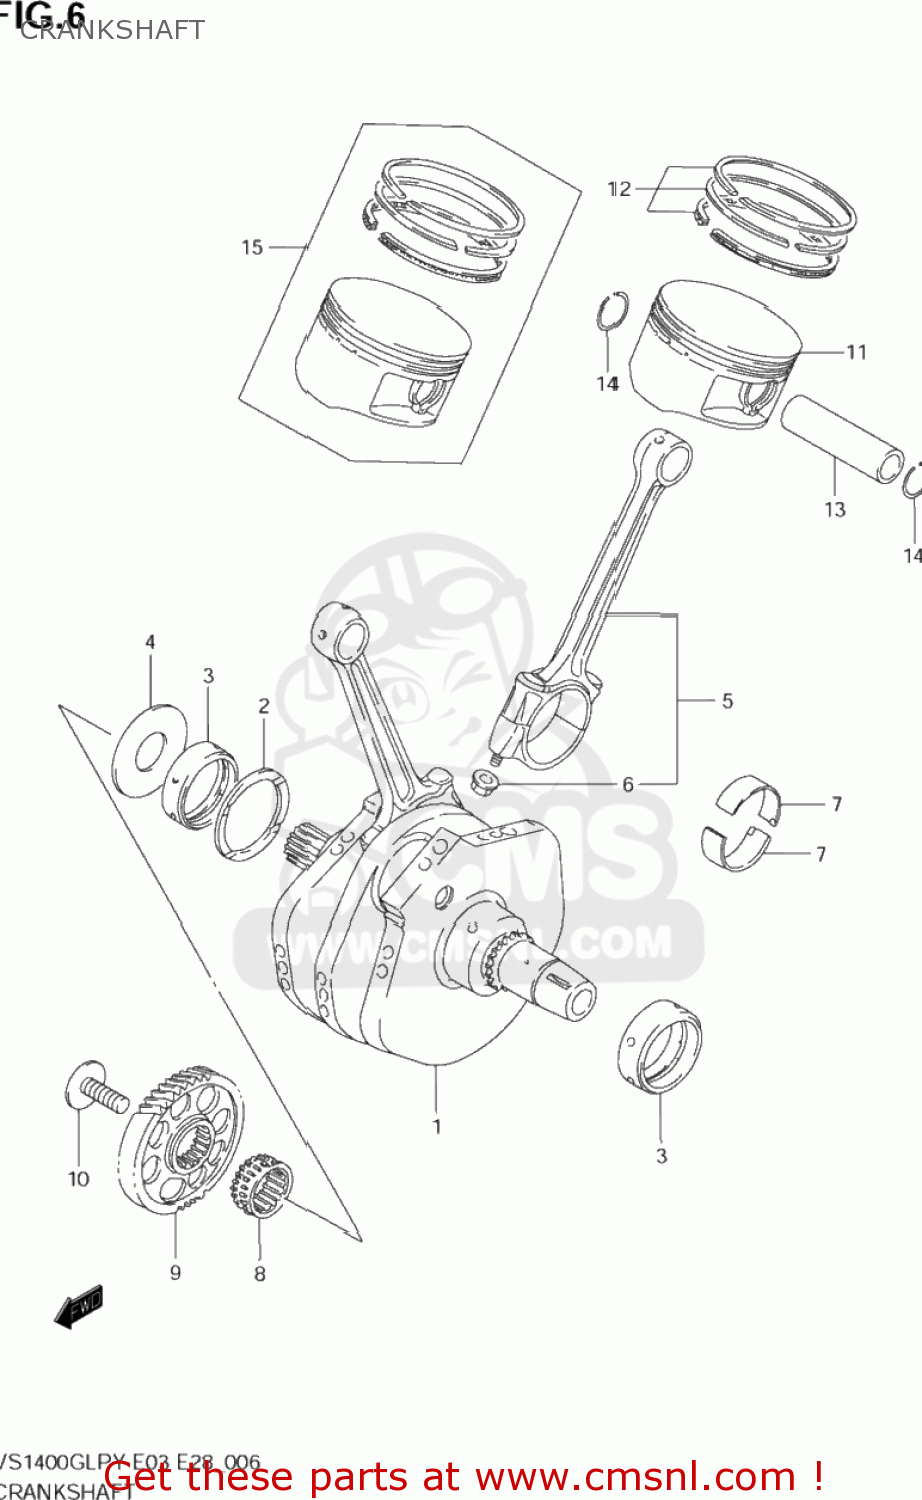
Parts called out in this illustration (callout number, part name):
1	CRANKSHAFT SET
2	PLATE,CRANK THRUST
3	METAL,CRANKSHAFT
4	WASHER,CRANK THRUST
5	CONNECTING ROD ASSY
6	NUT
7	METAL,CRANK PIN
8	SPROCKET,CAM CHAIN DRIVE,R
9	GEAR,PRIMARY DRIVE
10	BOLT(14X28)
11	PISTON
12	RING SET,PISTON
13	PIN,PISTON
14	CIRCLIP
15	PISTON SET(OS:0.5)
